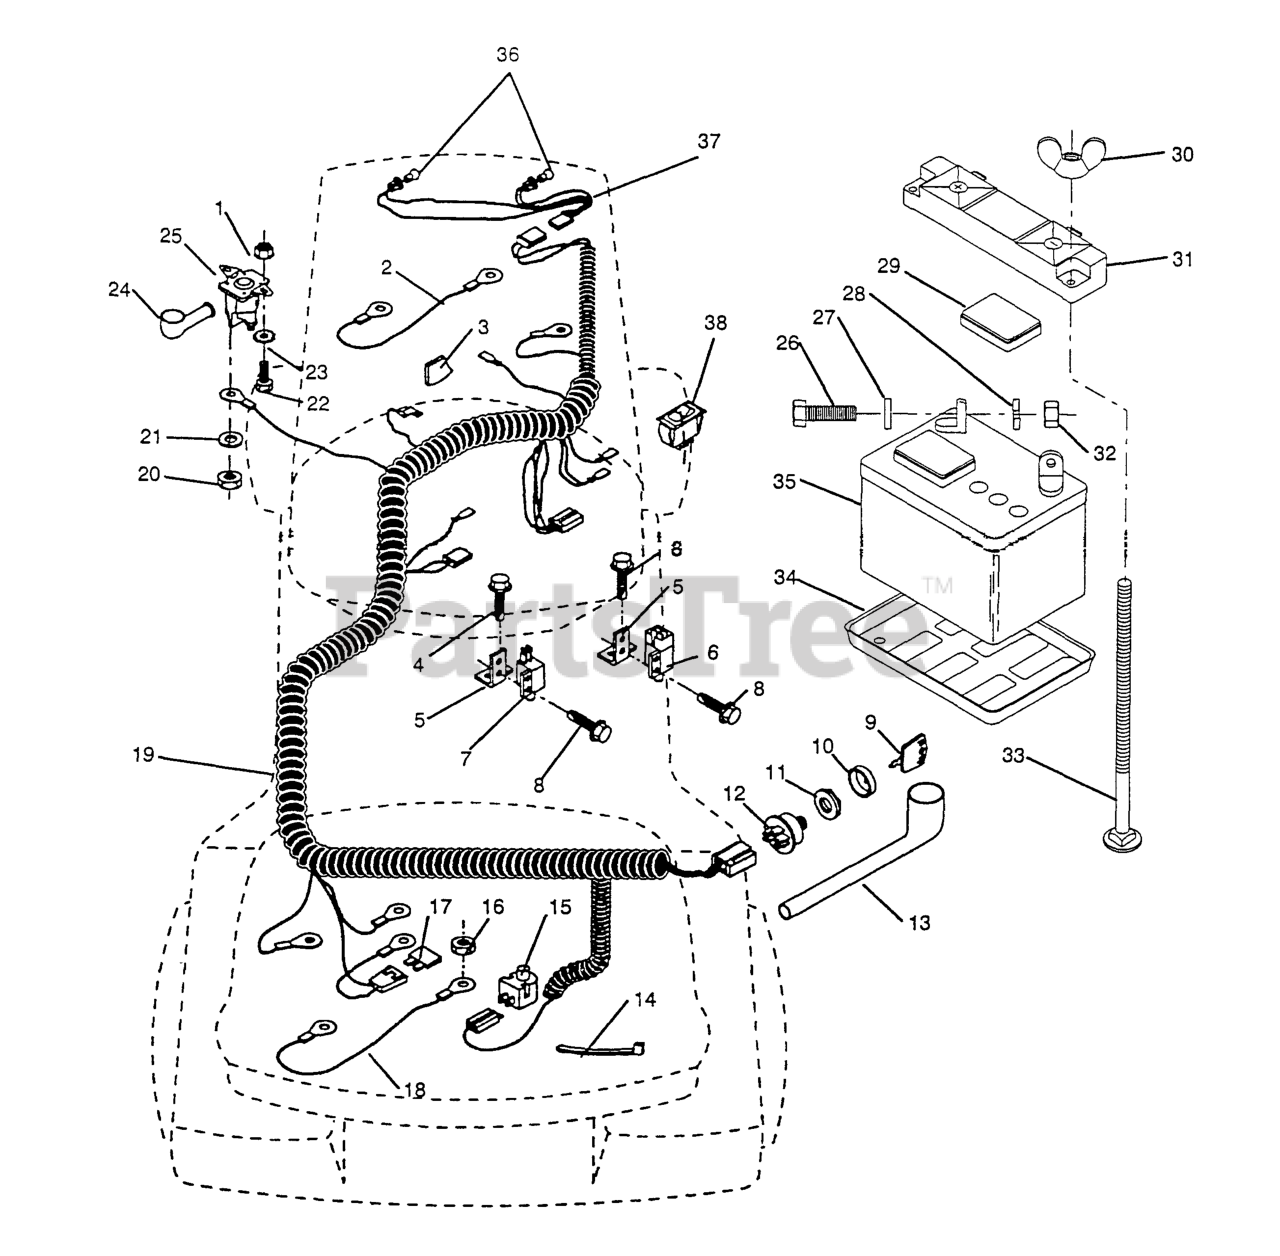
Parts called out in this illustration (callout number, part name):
1	NUT
3	STOP PLASTIC
4	Screw, Hex Wsh. Tap #10-16 x 1/2
5	BRACKET LT
6	SWITCH-INTER. GT
7	SWITCH INTERLOCKT
9	KEY.MOLDED.GENERIC
10	COVER KEY IGNITIO
11	NUT IGNITION
12	SWITCH
13	COVER IGNITION SW
14	TIE GUIDE
15	RP.SWITCH.PLUNGER.NC.GRAY
16	NUT
18	CABLE ASSY LT
19	HARNESS IGNITION
20	NUT
21	LOCKWASHER
22	BOLT
23	Washer, Lock Ext. Tooth 1/4
24	TERMINAL COVER
25	SOLENOID KIT
26	BOLT.HEX.1/4.X.3/4.DICHROMATE
27	WASHER
28	LOCKWASHER
29	CAP BATTERY NLA
30	WING NUT
31	TERMINAL GRD YTV
32	NUT
34	BATTERY TRAY T
35	BATTERY
36	BULB-LIGHT T
37	HARNESS LIGHT SOC
